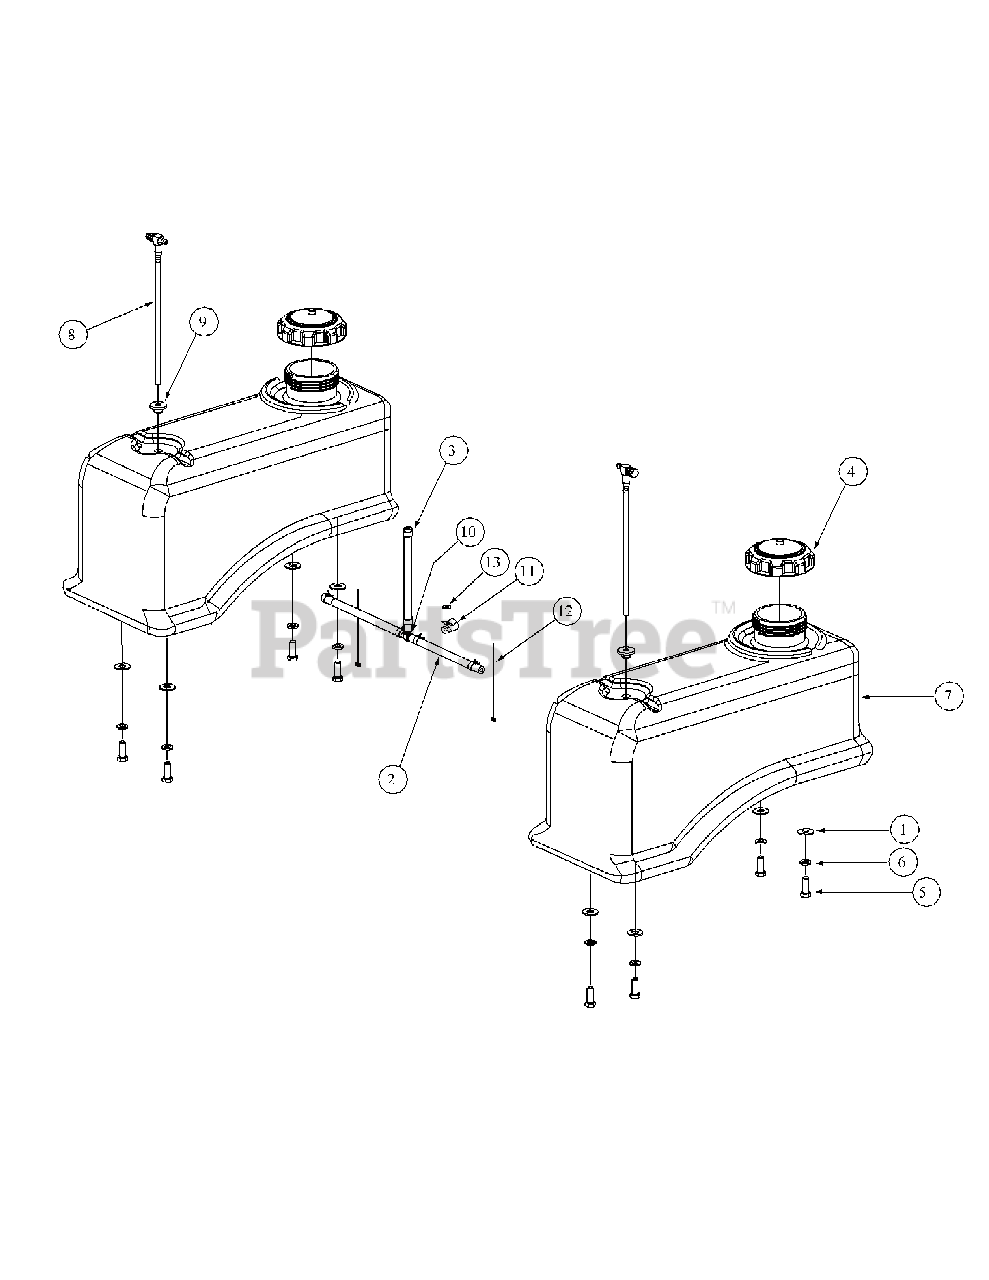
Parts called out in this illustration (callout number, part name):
1	Flat Washer, .406 ID, 1.0 OD, .105
2	Hose, 1/4" Fuel Line 79.5 inches
3	Clamp, Union
4	Fuel Cap, 3.5
5	Hex, Cap Screw, 3/8-16, .88
6	Lock Washer, 3/8
7	Fuel Tank
8	Fuel Fitting
9	Grommet, Fuel Tank
10	Tee Fitting, Fuel
11	Clamp, 1/2 Tubing
12	Cable Tie
13	Flat Washer, 1.4 x .630 x .0515
